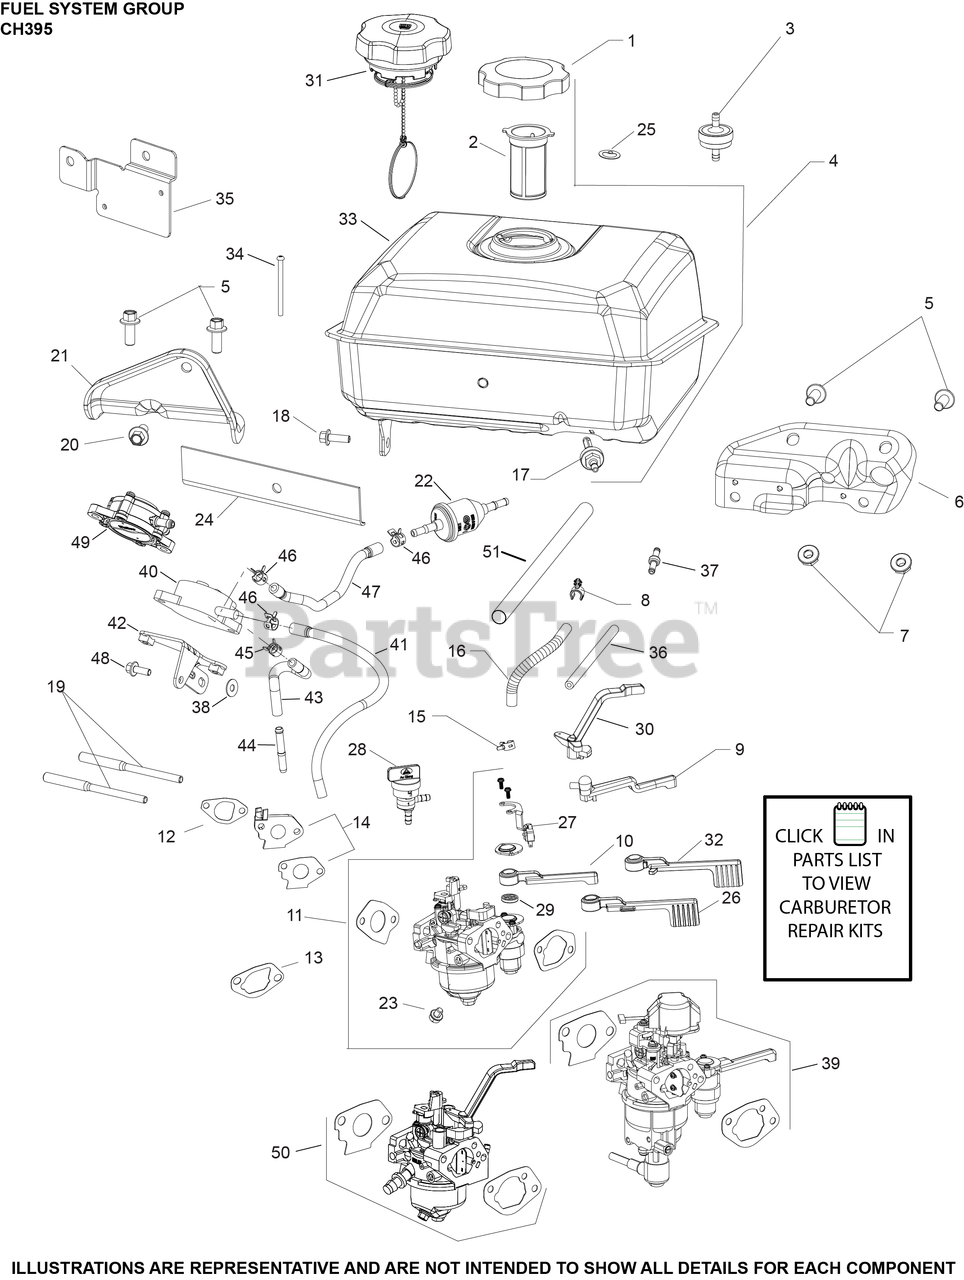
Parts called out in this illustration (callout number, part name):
2	FILTER, FUEL TANK
5	SCREW, M8 X 20
6	BRACKET, FUEL SUPPORT ASSEMBLY
7	NUT, FLG M8X1.25
8	CLIP, FUEL HOSE
9	LEVER, CHOKE
10	LEVER, FUEL SHUTOFF
11	KIT, CARBURETOR
14	INSULATOR AND GASKET KIT
15	CLAMP, FUEL LINE
16	LINE, FUEL (10"-CUT TO LENGTH)
17	FITTING, FUEL ASSY
18	SCREW, M6 X18
19	STUD, CARBURETOR
20	SCREW, FLG 8X1.25X16
21	BRACKET, FUEL SUPPORT
23	SCREW, BOWL DRAIN (CKY)
25	KIT, FUEL SCREEN
29	SEAL, INLET VALVE
31	FUEL CAP, ASSEMBLY USE 17 173 19-S
33	TANK, FUEL
NI	KIT, HIGH ALTITUDE (4,000-8,000 FT)
NI	KIT, HIGH ALTITUDE (ABOVE 8,000 FT.)
NI	KIT, CARBURETOR REPAIR
